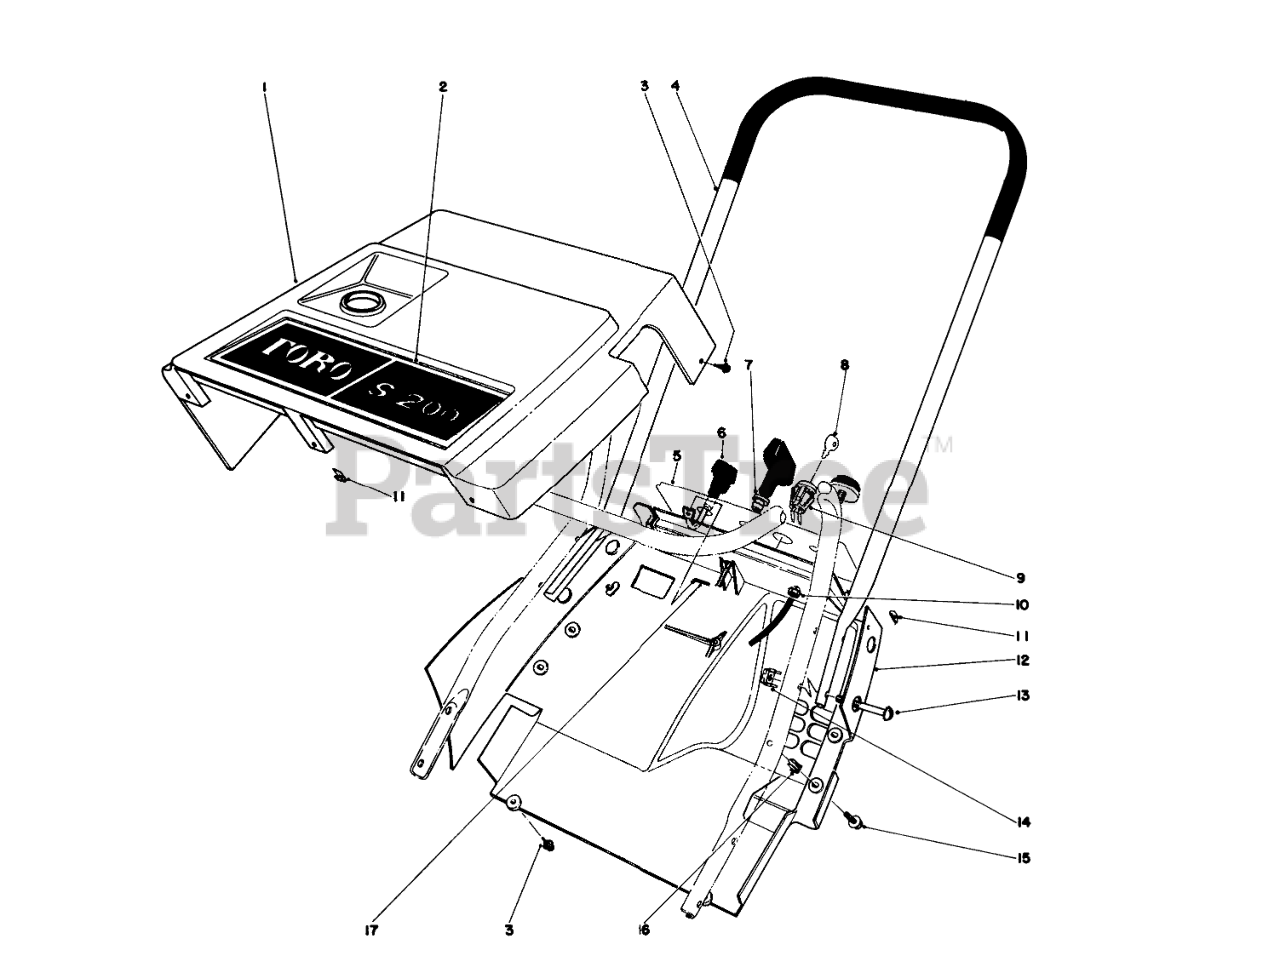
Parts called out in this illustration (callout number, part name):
1	Shroud-Upper
2	TORO DECAL
3	SCREW-HWHTF
4	Upper Handle
5	Decal-Control Panel
6	CHOKE CONTROL ASM
7	GUIDE-ROPE, STARTER
8	Key
9	Switch
10	Locknut
11	NUT-TYPE J
12	Lower Shroud
13	Sems Mach. Screw
14	TINNERMAN NUT
15	SCREW-HWHTF
16	PUSH IN NUT
17	CONTROL WIRE
